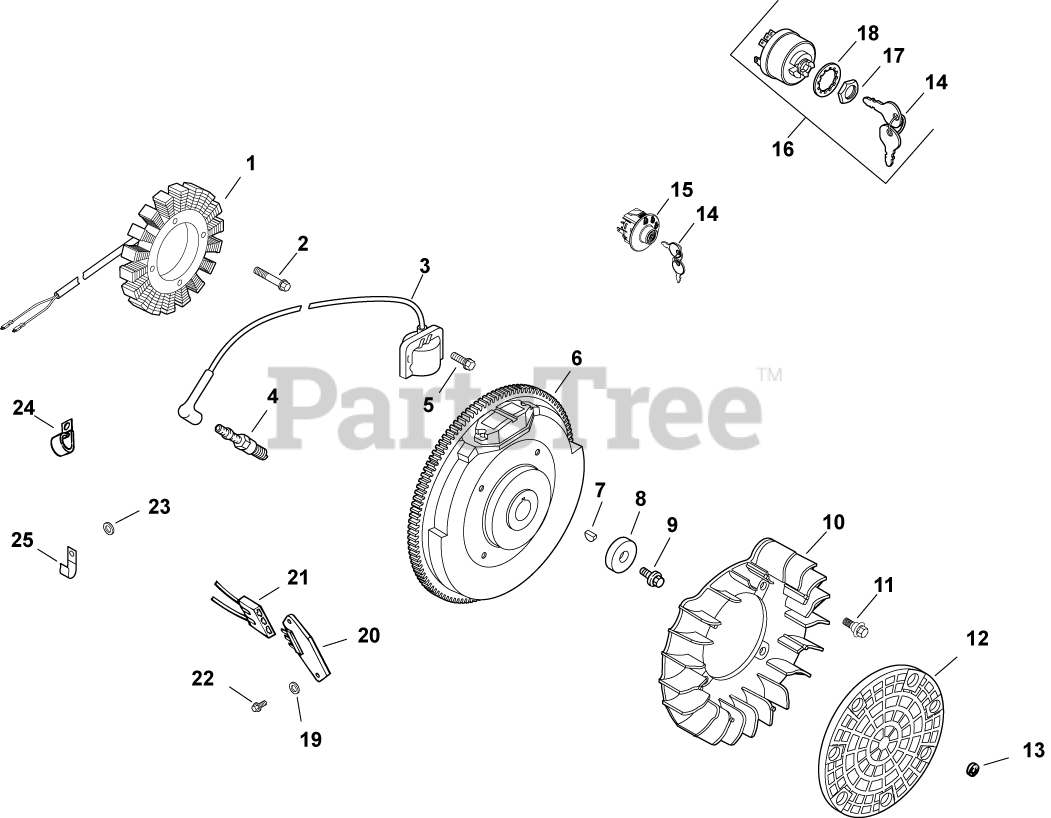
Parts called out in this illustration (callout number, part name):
1	KIT, 15 / 20 AMP STATOR
2	SCREW, M5X0.8X25 - (#25086402S)
3	KIT, MODULE IGNTN (CDI FIXED)
4	PLUG, SPARK (STD)
5	SCREW, FLG THD FRM M5X.8X20-(#25086399S)
6	FLYWHEEL, PAINTED-USE 24 025 55-S
7	KEY, 3/16" X 5/8"
8	WASHER, FLAT 13/32"
9	SCREW, FLG M10X1.5X45 - (#25086361S)
10	FAN - USE (#24 157 11-S)
11	BOLT, SHOULDER
12	SCREEN, GRASS
14	KEY, SET -USE 48 340 01-S
15	KIT, KEY SWITCH (SNAP-IN)
16	SWITCH ASSY, KEY (KM)-USE 25 099 32-S
17	NUT, KEY SWITCH
18	WASHER, INTERNAL TOOTH
19	WASHER, FLAT 3/16"
20	REG/RECT-15 AMP (KM)-USE 41 403 10-S
21	CONNECTOR, BODY (KM)-USE 25 155 41-S
22	SCREW, PHL HD #11-16X7/8"
23	WASHER, FLAT 1/4" (O.D. 1/2")
24	CLIP, TUBE & WIRING (KM)
25	CLIP, CABLE
2417641-S	LEAD, DUPLEX
2451809-S	LEAD, OIL SENTRY
2546807-S	WASHER, FLAT 7/32"
24126137-S	BRACKET, GROUND STRAP USE 24 518 12-S
24176112-S	HARNESS, WIRING-USE 24 176 150-S
